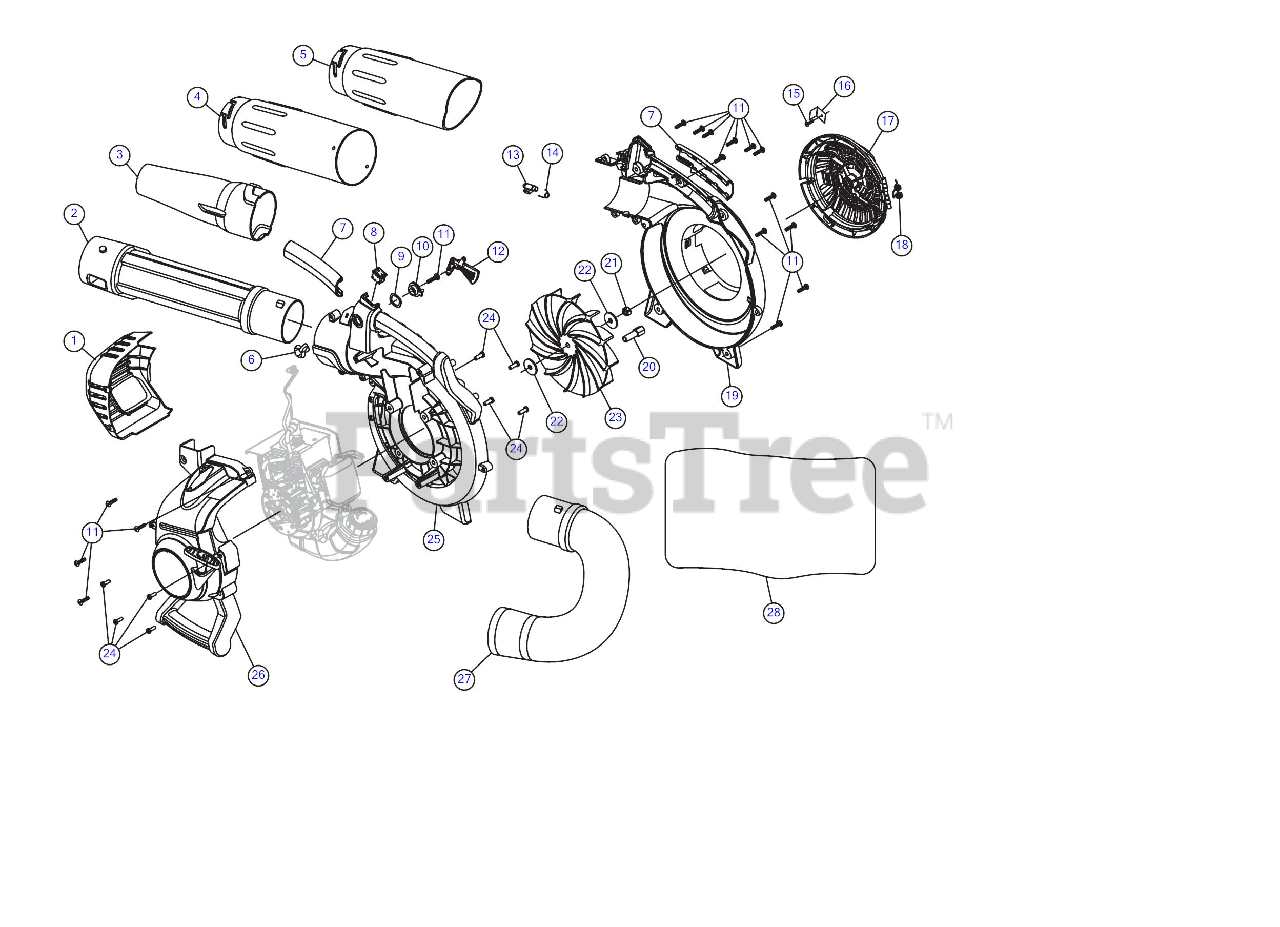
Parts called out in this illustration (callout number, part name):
1	Muffler Cover Assembly (Incl. 11)
2	Upper Tube
4	Upper Vac Tube
5	Lower Vac Tube
6	Outer Trigger Lock
7	Handle Grips
9	Wavey Washer
10	Inner Trigger Lock
12	Throttle Trigger
13	Latch Tube
14	Latch Spring
17	Intake Cover
19	Impeller Housing
21	Nut
24	Screw
25	Impeller Housing
26	Engine Cover Assembly (Incl. 11 & 24)
